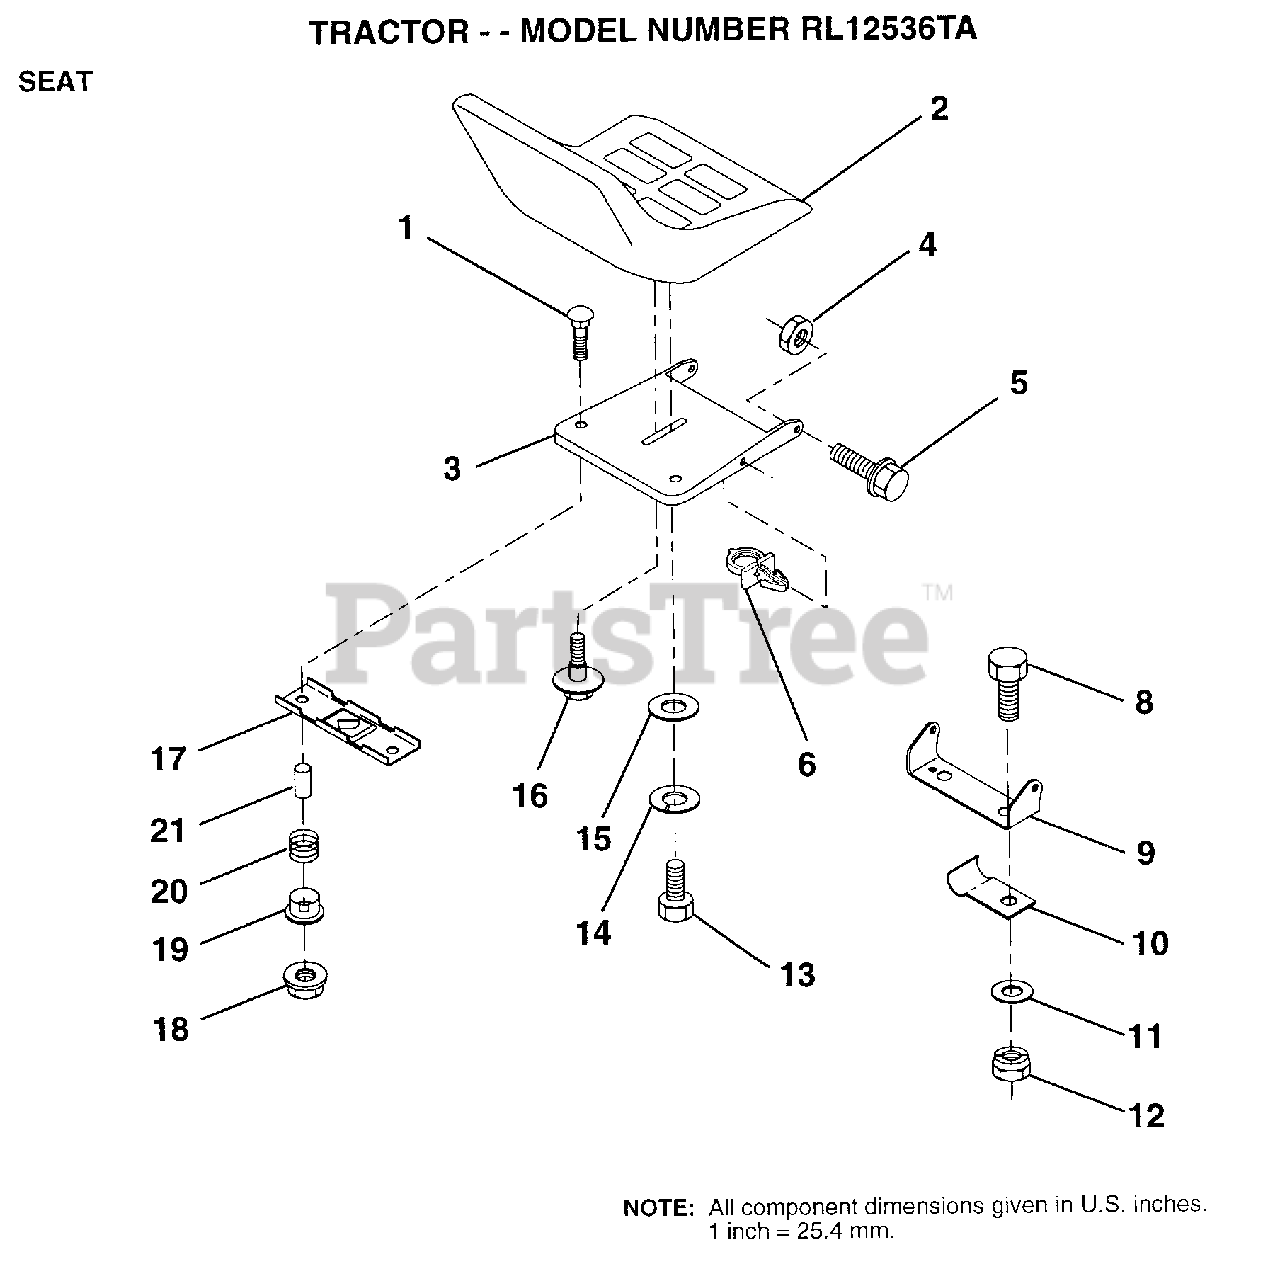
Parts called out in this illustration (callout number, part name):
4	NUT
5	BOLT.SHLD.5/16-18
6	CLIP.PUSH-IN.HING
8	BOLT
9	BRACKET PVT SEAT
10	"CLIP,INSULATOR"
11	WASHER
12	NUT
13	BOLT
14	LOCKWASHER
15	WASHER
16	"BOLT,SHOULDER"
17	BRKT SWITCH
19	BUSHING
20	SPRING
21	SPLIT SPACER
